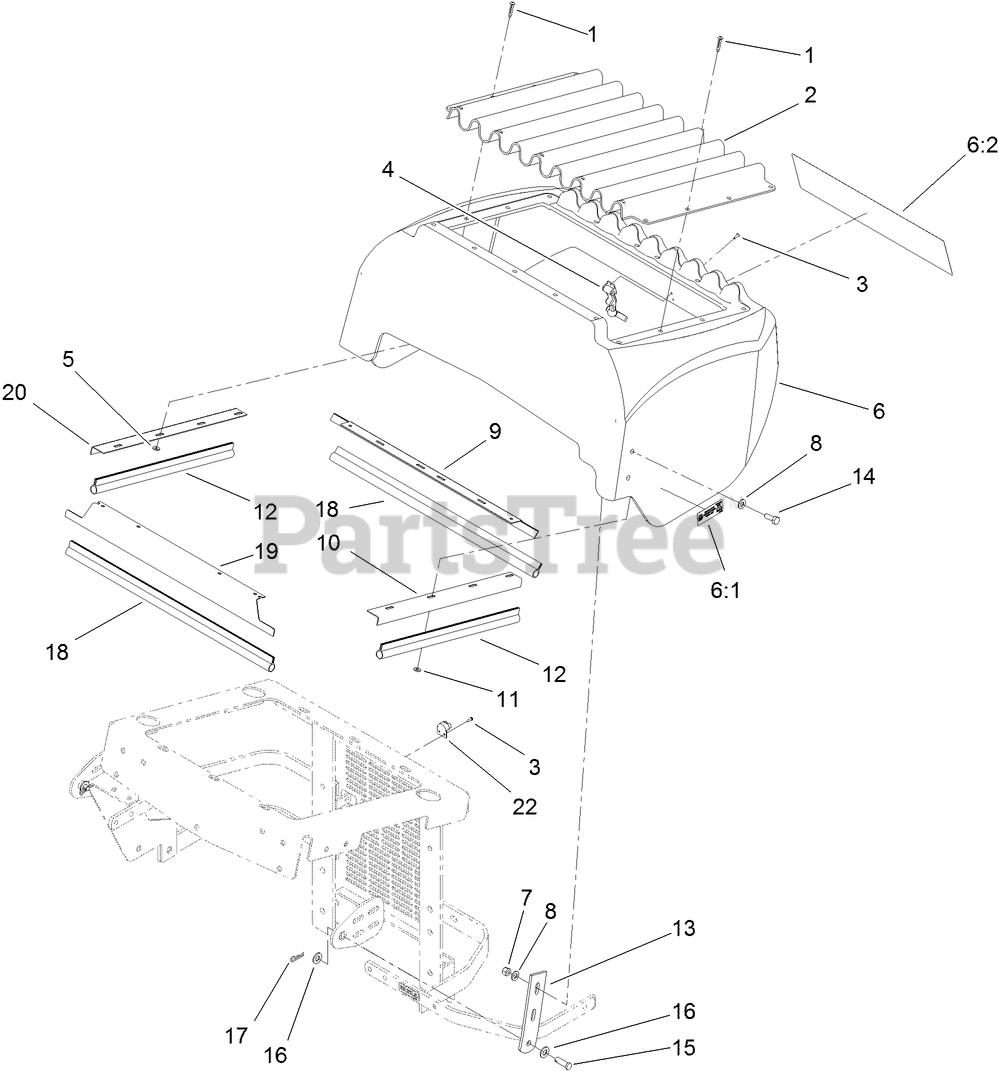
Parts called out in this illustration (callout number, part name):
2	SCREEN-RADIATOR
3	RIVET
4	LATCH-RUBBER
5	WASHER-SPRING
6	HOOD ASM
6:1	DECAL-LOW SULFUR
7	NUT-LOCK, NI
8	WASHER-PLAIN
9	ANGLE-RADIATOR, BOTTOM
10	ANGLE-RADIATOR, LH
11	WASHER-FLAT
12	SEAL-TRIM
13	PLATE-HINGE, HOOD
14	SCREW-HH
15	PIN-CLEVIS
16	WASHER-FLAT
17	PIN-COTTER
18	SEAL-TRIM
19	ANGLE-RADIATOR, TOP
20	ANGLE-RADIATOR, RH
